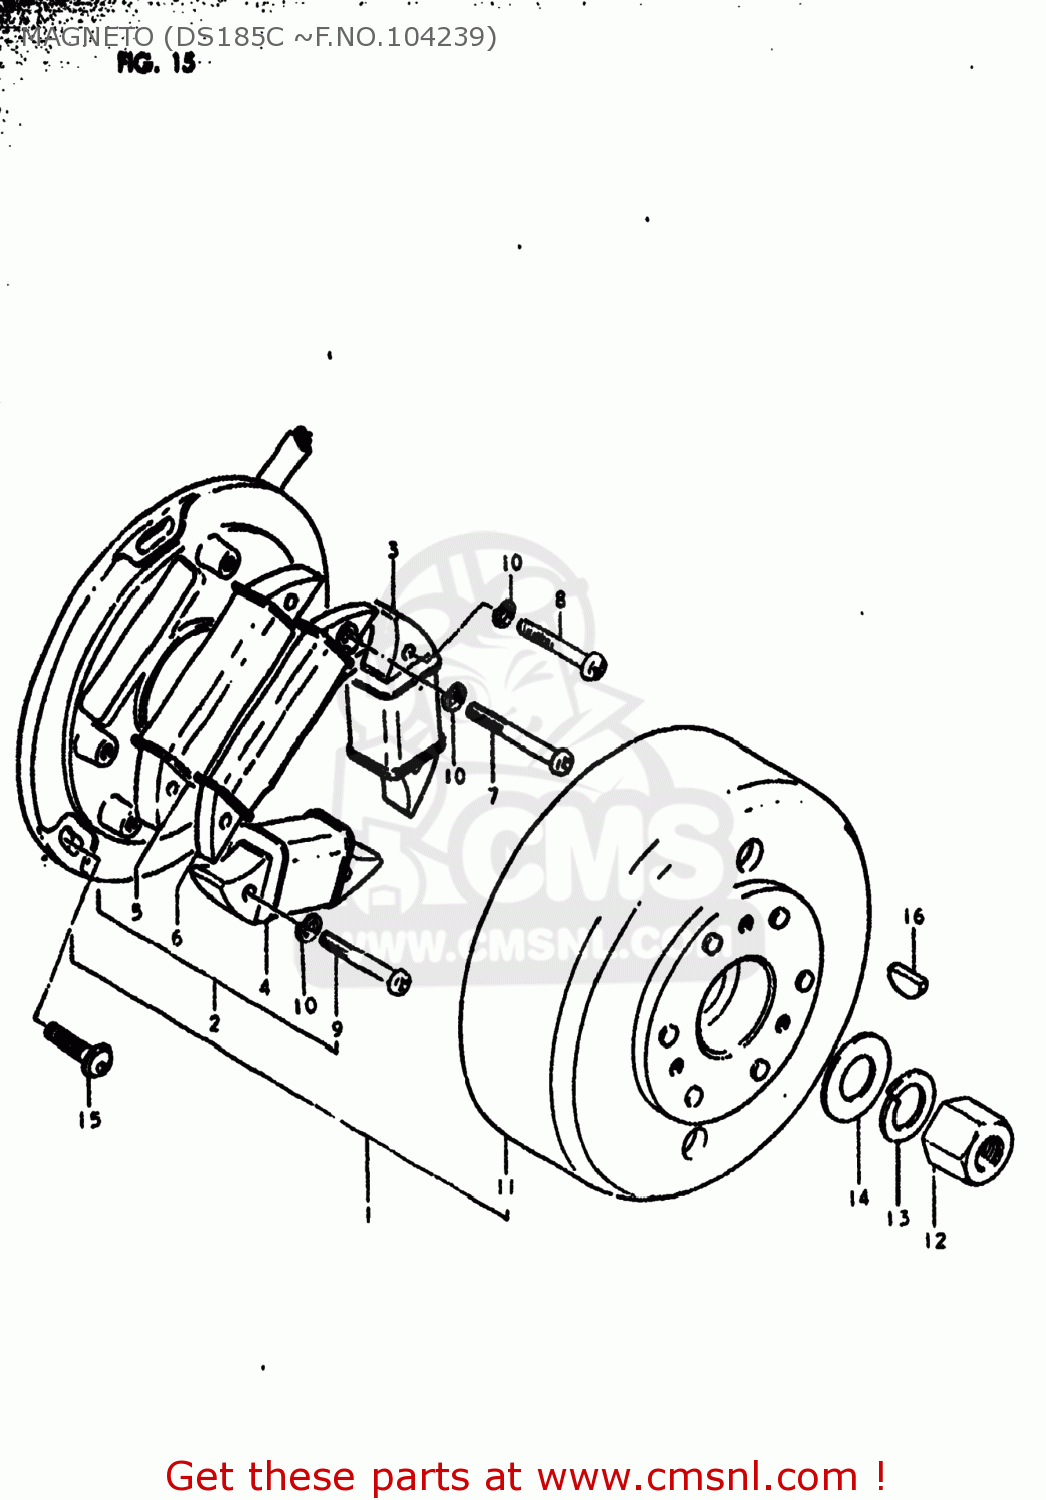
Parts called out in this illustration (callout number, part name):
1	MAGNETO ASSEMBLY
2	STATOR ASSEMBLY
3	COIL,LIGHTING
4	COIL
5	COIL
6	COIL,PULSER
7	SCREW 5X35
8	SCREW
9	SCREW 5X20
10	LOCK WASHER
11	ROTOR ASSEMBLY
12	NUT
13	LOCK WASHER
14	WASHER(14X27X3)
15	SCREW(5X14)
16	KEY 4MM
